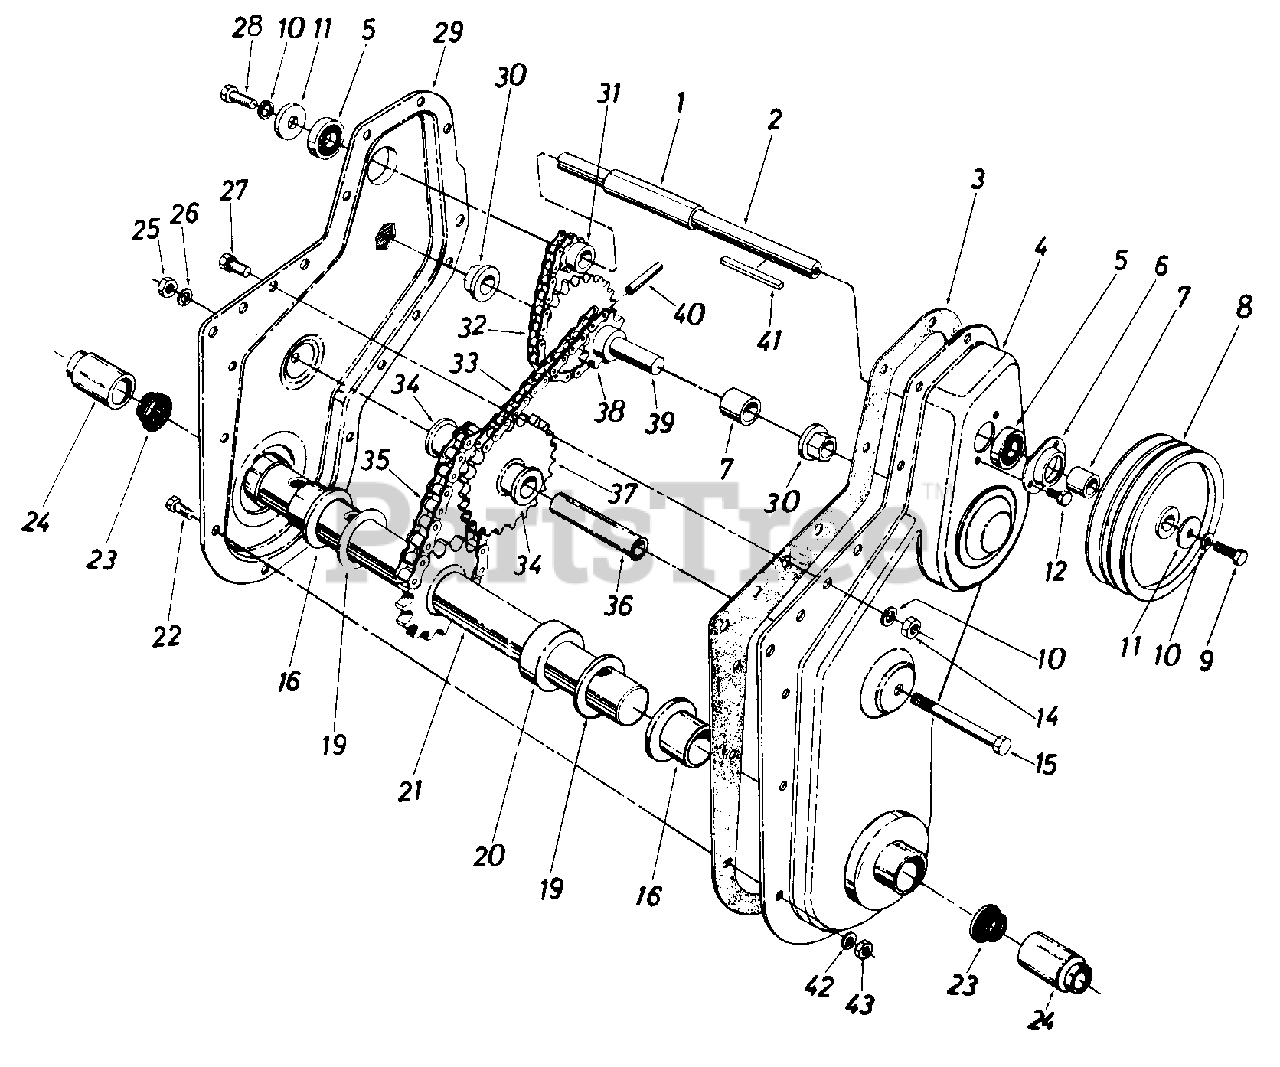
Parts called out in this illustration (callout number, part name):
1	Spacer .657 I.D. x .78 O.D. x 2.19" Lg.
2	Jackshaft
3	Housing Gasket
4	Housing Ass'y. L.H. Half
5	Ball Bearing .625 I.D. x 1.375 O.D.
6	Bearing Housing
7	Spacer .635 I.D. x .88 O.D. x 1.03" Lg.
8	Chain Case Pulley 6.0" Dia.
9	Hex Bolt 5/16-18 x 1.0" Lg.
10	L-Wash. 5/16" I.D.*
11	Fl-Wash. .344" I.D. x 1.125 O.D.
12	Hex Wash. Hd. Self-Tap Scr. 1/4-20 x .50" Lg.
14	Hex Nut 5/16-18 Thd.
15	Hex Bolt 3/8-16 x 3.25" Lg.
16	Flange Bearing (Plastic)
19	Flat Thrust Wash.
20	Step Spacer
21	Tine Shaft Ass'y.
22	Hex Bolt 1/4-28 x .62" Lg.
23	Seal Ring
24	Dust Cap
25	Hex Nut 3/8-16 Thd.
26	L-Wash. 3/8" I.D.
27	Hex Sems Bolt 5/16-18 x 1.00" Lg.
28	Hex Bolt 5/16-18 x .62" Lg.
29	Housing Ass'y. R.H. Half
30	Hex Flanged Bearing
31	Sprocket 10 Teeth 1/2" Pitch
32	#41 Chain 1/2" Pitch x 34 Links
33	#420 Chain 1/2" Pitch x 48 Links
34	Flange Bearing .625" I.D.
35	#50 Chain 5/8" Pitch x 28 Links
36	Sprocket Shaft
37	Sprocket Bearing Sleeve Ass'y.
38	Sprocket Sleeve Ass'y.
39	Sprocket Shaft
40	Spring Pin Spiral 1/4" Dia. x 1.5" Lg.
41	Square Key 3/16 x 3/16 x 1.50" Lg.
42	L-Wash. 1/4" I.D.
43	Hex Nut 1/4-28 Thd.
